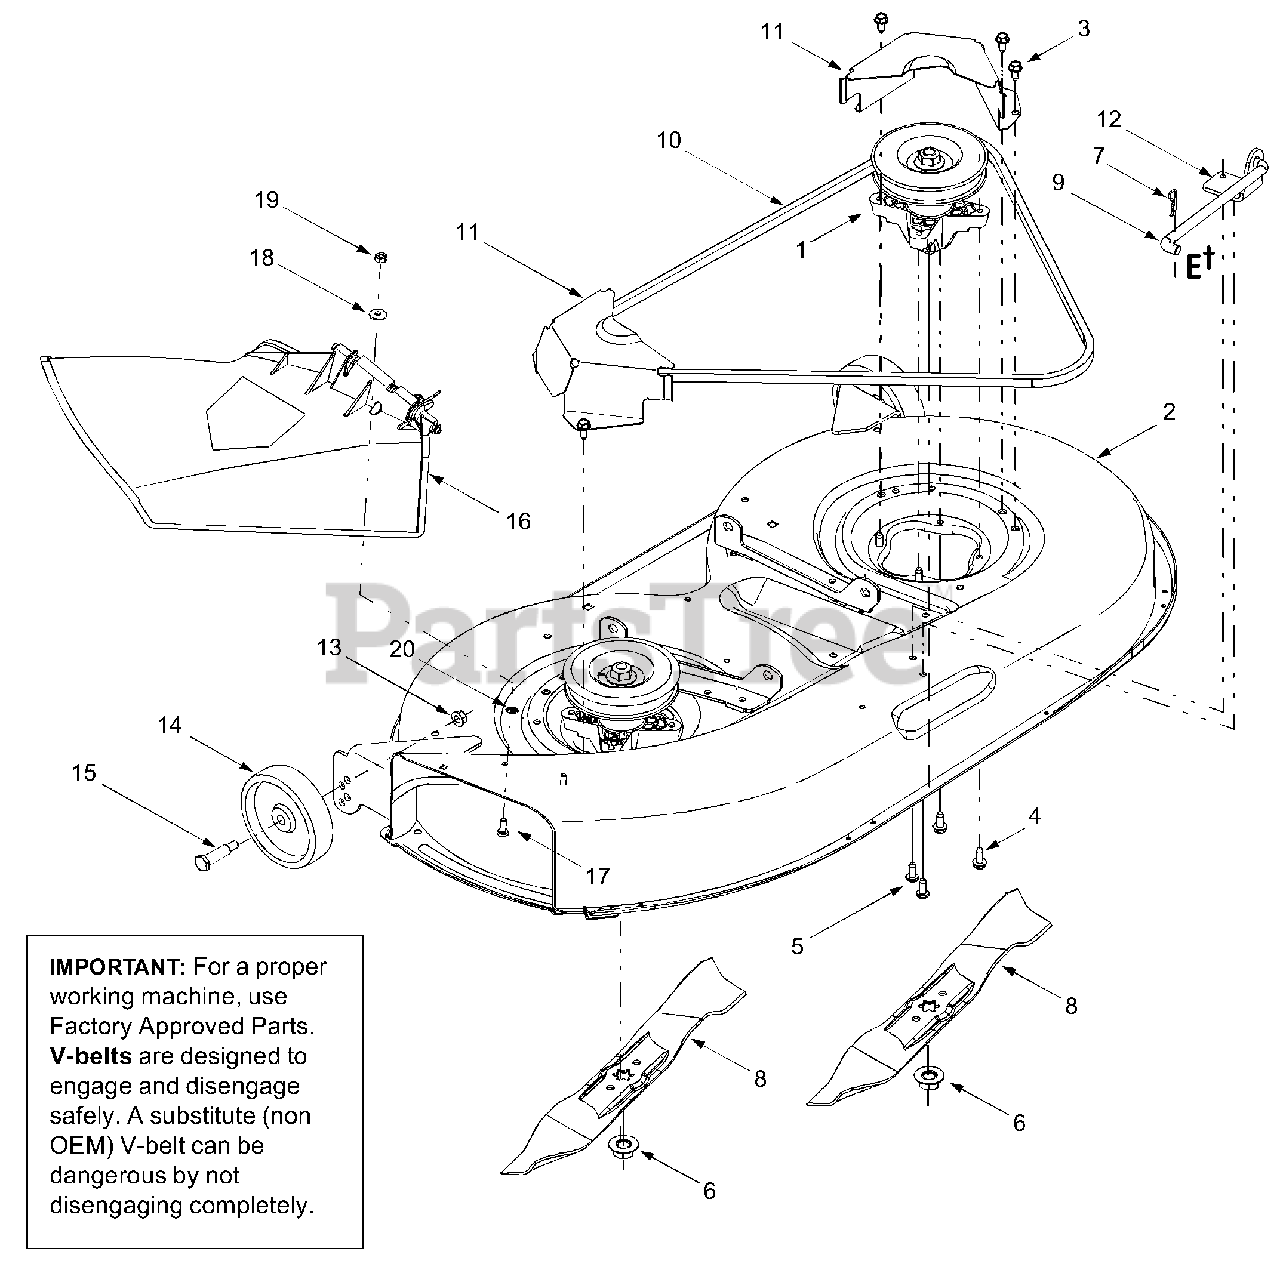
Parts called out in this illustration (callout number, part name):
1	Spindle Assembly
4	Screw, 5/16-18 x .75
5	Self-tapping Screw, 5/16-18 x .75
6	Hex Flange Nut, 5/8-18
7	Internal Cotter Pin, .080 x 1.56
8	Blade, 21.23"
9	Deck Hanger Link/Anti-sway Rod
10	Deck Belt
13	Flange Lock Nut, 3/8-16
14	Deck Wheel, 5 x 1.38
15	Shoulder Screw, .498 x 1.53
16	Discharge Chute Assembly
17	Hex Cap Screw:1/4-20 x .620
18	Bell Washer, .265 x .75 x .062
19	Hex Nut, 1/4-20
20	Push Nut, 1/4
